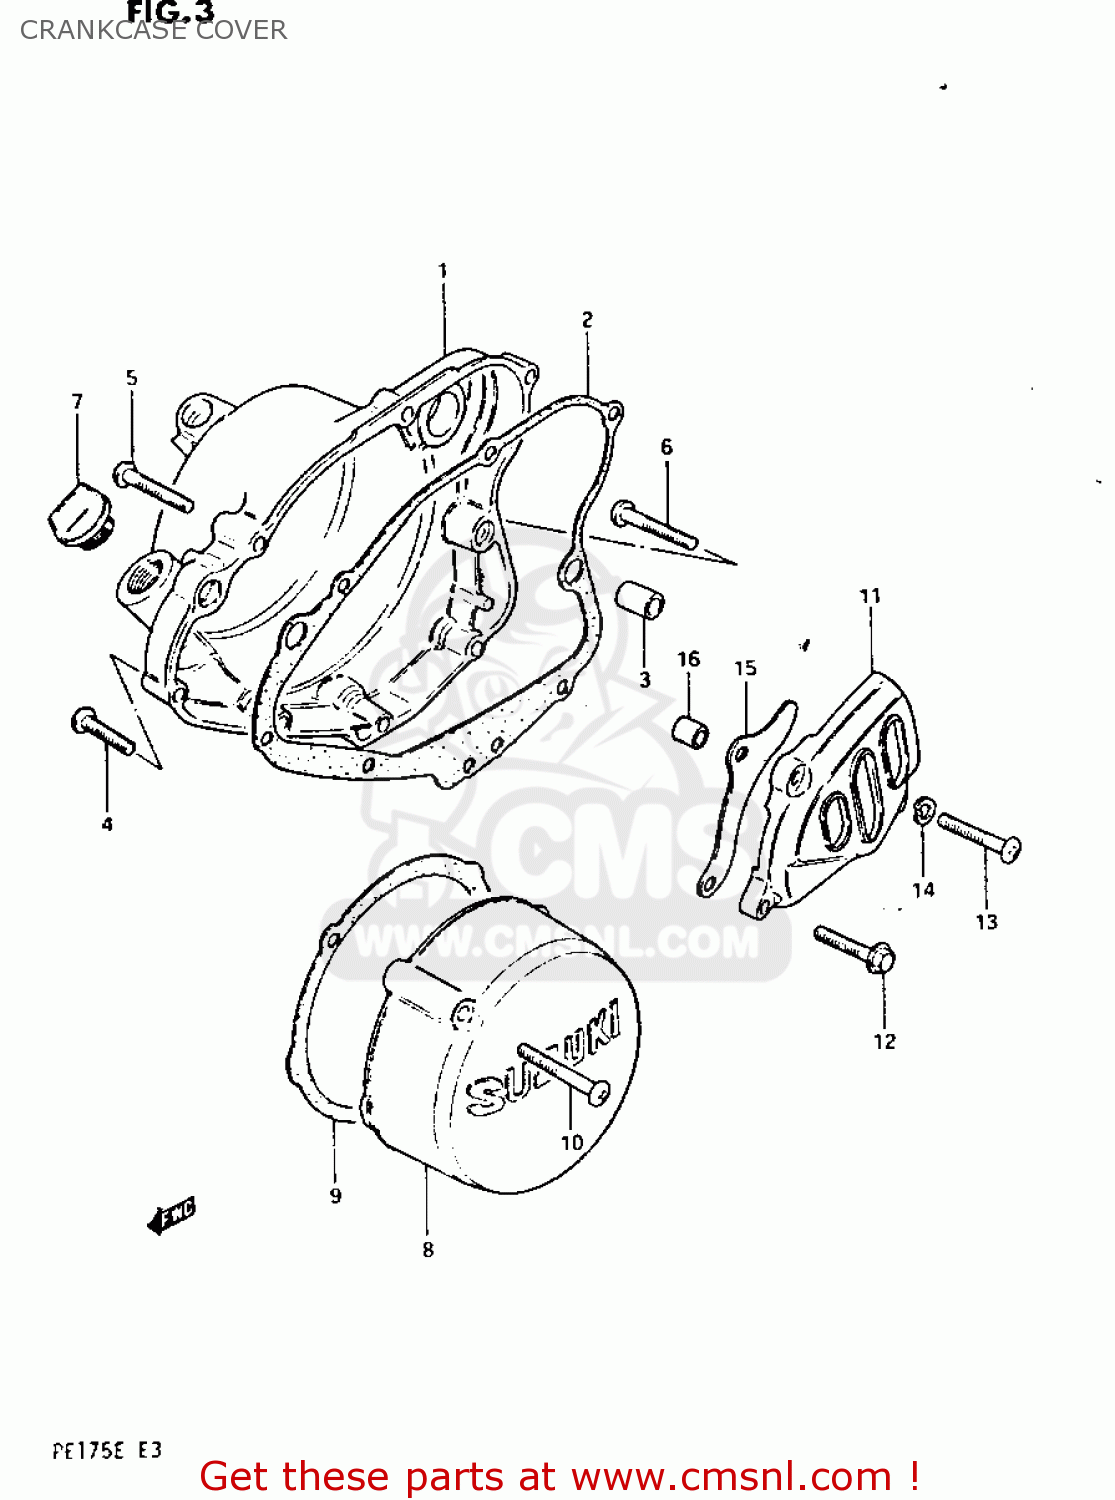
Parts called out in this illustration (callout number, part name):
1	COVER,CLUTCH
2	GASKET,CLUTCH COVER (NAS)
3	PIN
4	SCREW
5	SCREW
6	SCREW
7	PLUG SET
8	COVER,MAGNETO
9	GASKET,MAGNETO COVER (NAS)
10	SCREW
11	COVER,ENGINE SPROCKET
12	BOLT 6X35
13	SCREW
14	WASHER,LOCK
15	PLATE,FRONT CHAIN GUIDE
16	SPACER(6.5X10.5X12)
